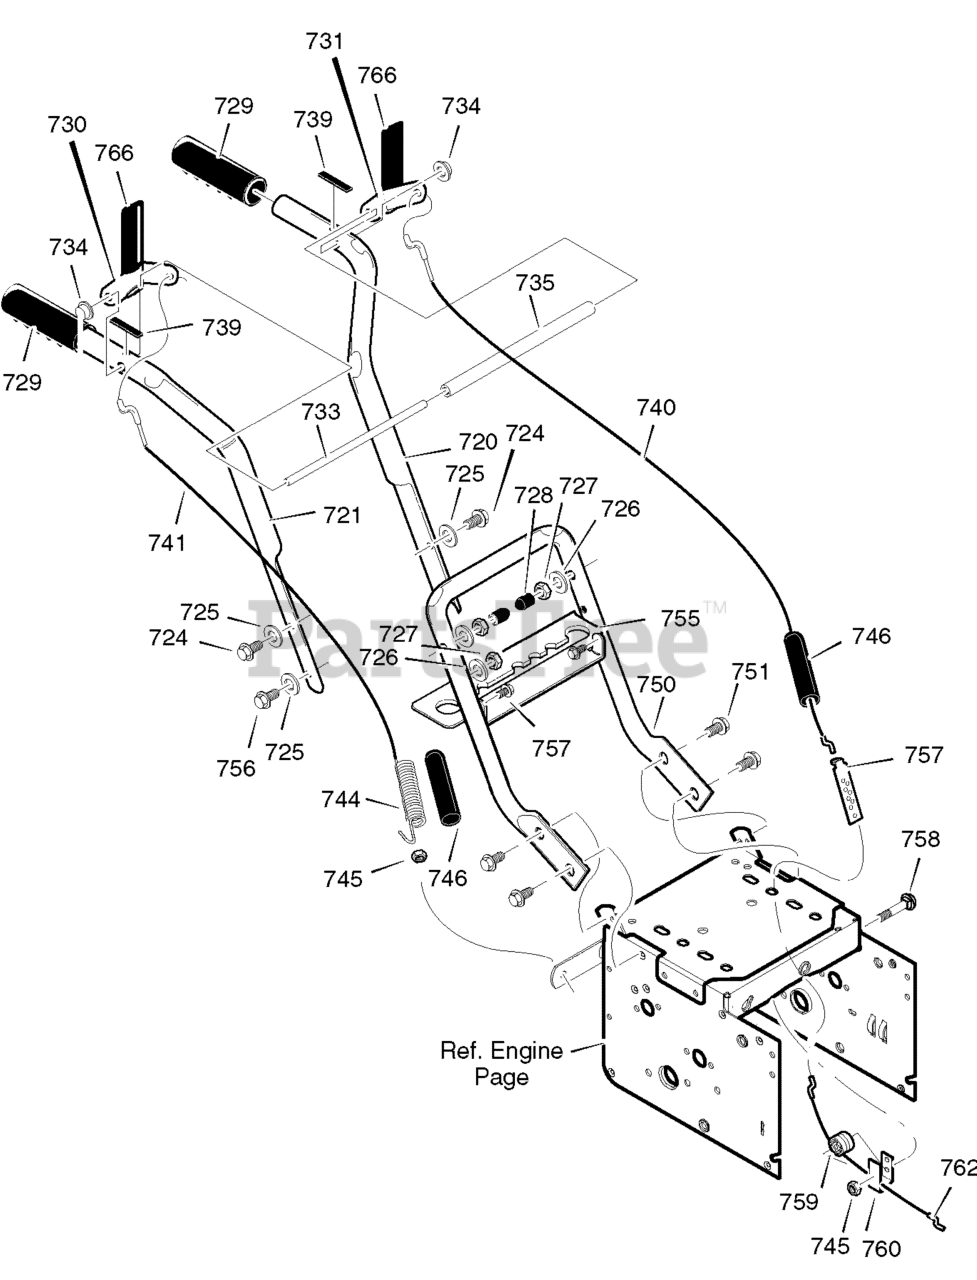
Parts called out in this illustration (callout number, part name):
720	HANDLE, UPPER LH
721	HANDLE, UPPER RH
724	SCREW, 5/16-18 X 2.75
725	WASHER, FLAT
726	WASHER, SPTLK .31X.58X.08
727	NUT, 5/16-18 REGHEX YZ
728	STOP, RED PLASTIC
729	GRIP-HANDLE FINGER
730	LEVER, ASSY CLUTCH DRIVE RH
731	LEVER, ASSY CLUTCH DRIVE LH
733	ROD, PIVOT CLUTCH
734	NUT, PUSH ON CAP
735	SPACER-HANDLE
739	BUMPER, RECTANGLE
740	CABLE, CLUTCH
741	CABLE, AUGER CLUTCH
743	BRACKET, CABLE ADJUSTER
744	SPRING, AUGER CLUTCH
745	NUT, 1/4-20 NYLOCK YZ
746	BOOT, CABLE SPRING
750	HANDLE, LOWER
751	SCREW, TAP 5/16-18 x 3/4
755	BRKT, GEAR SELECTOR
756	SCREW, 5/16-18 X 2.00
757	SCREW, 1/4-20 x 0.63
758	BOLT, HEX 1/4-20 X 1.50
759	SPOOL-CABLE, AUGRT CLUTCH
760	BRACKET, CABLE SPOOL YZ
762	CABLE, LOWER DRIVE 12"
766	GRIP, CLUTCH HANDLE
